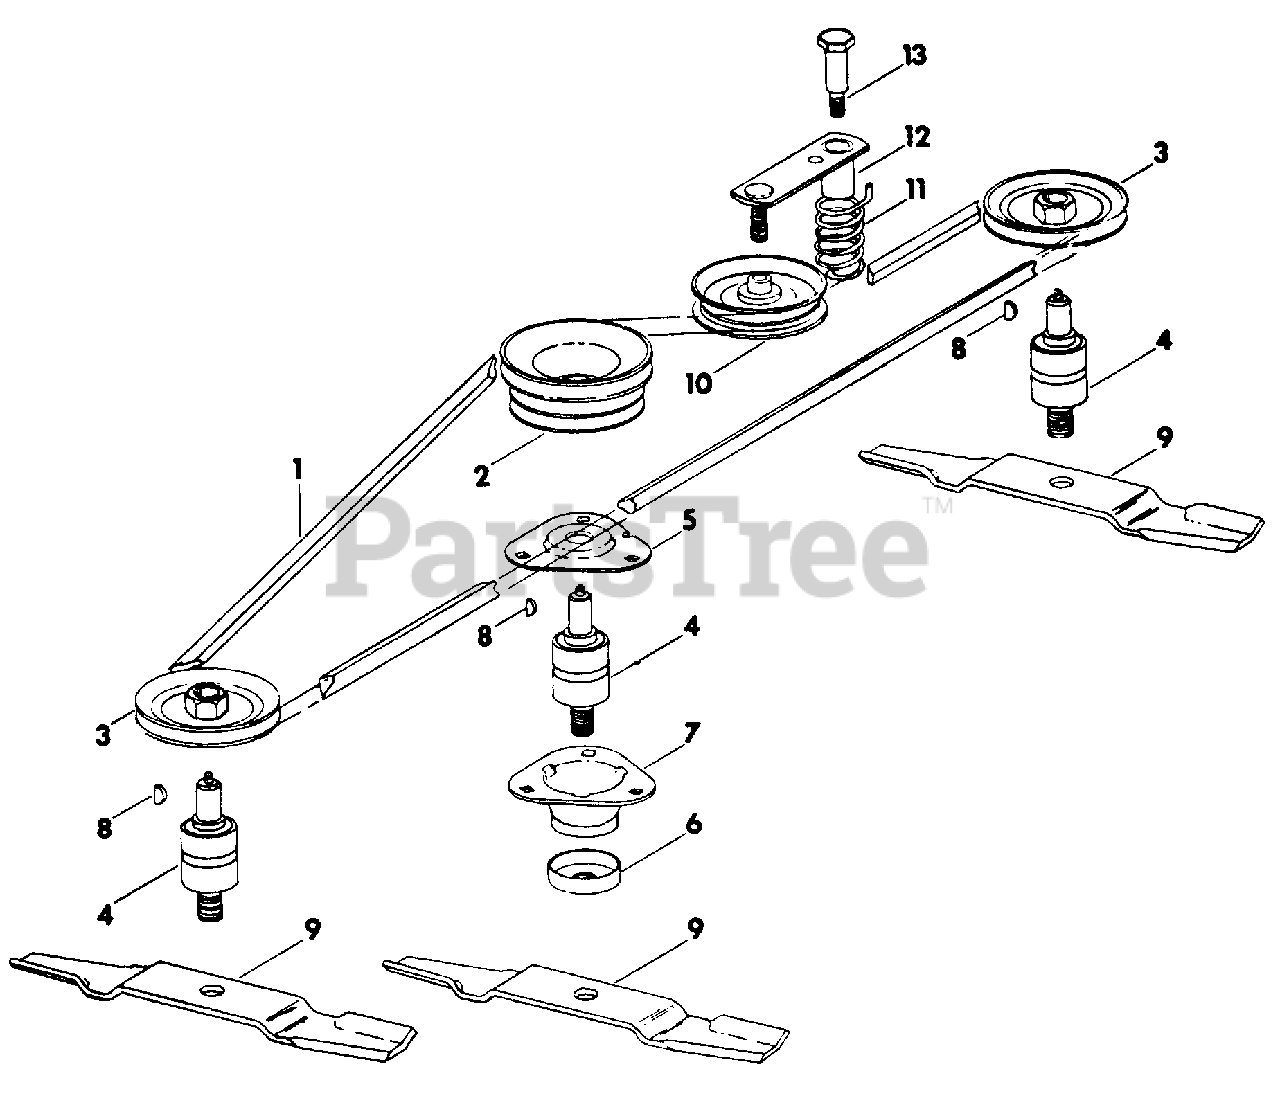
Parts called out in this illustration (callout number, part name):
1	Belt, Spindle Drive
2	Pulley, Center
3	Pulley, Outer
4	Bearing, Ball
6	Cup, Spindle
7	Housing, Spindle
8	Key, 1/4 X 3/4 Woodruff 91
9	Blade, 44 In. Mower Hard Surface
10	Pulley, Flat Idler
11	Spring, Torsion
12	Arm Assy, Idler
13	Bolt, Idler Arm Pivot
